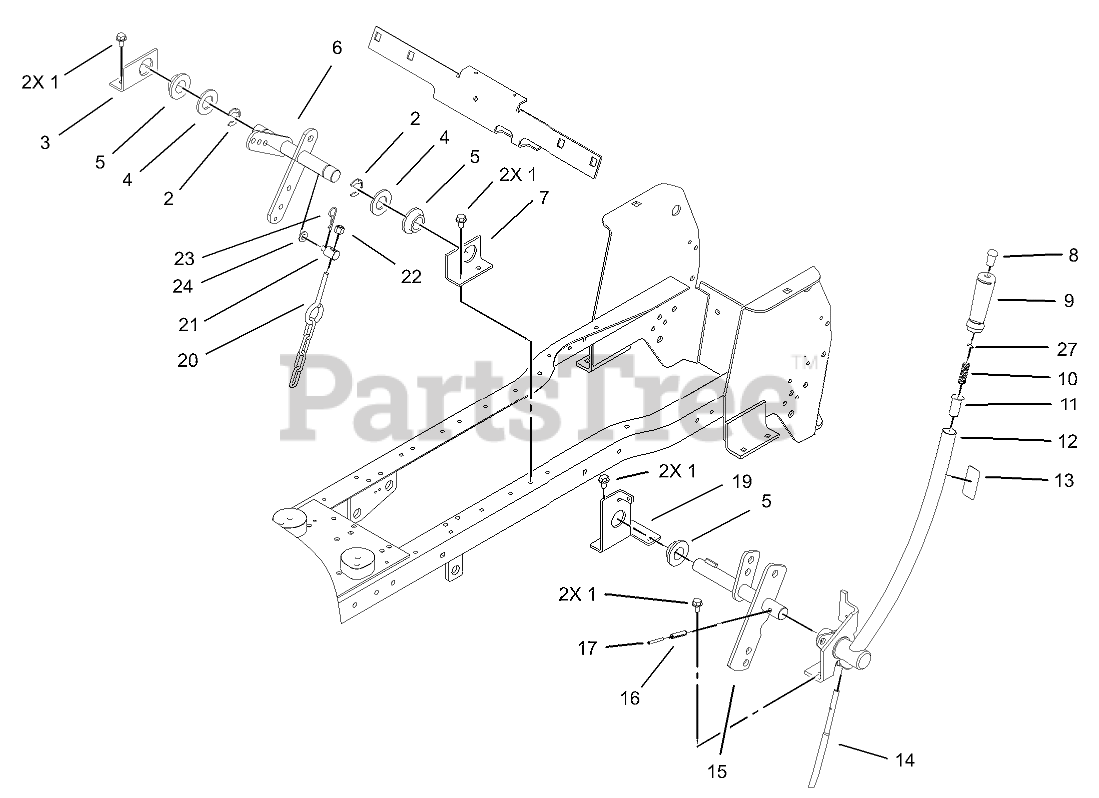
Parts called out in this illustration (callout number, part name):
1	SCREW-HWHTF
2	RING-RETAINING
3	BRACKET-PIVOT LINKAGE, RH
4	WASHER-FLAT
5	BEARING-FLANGE
6	LIFT LEVER ASM
7	BRACKET-PIVOT LINKAGE, LH
8	TIP-ROD
9	GRIP-HANDLE
10	SPRING-COMPRESSION
11	RETAINER-SPRING
12	LIFT LEVER ASM
13	DECAL-LIFT
14	ROD-LEVER, LIFT
15	LIFT ARM ASM
16	PIN-ROLL
17	PIN-SPRING
19	BRACKET-PIVOT, LIFT
20	CHAIN-LIFT
21	TRUNNION
22	NUT-LOCK, NI
23	PIN-HAIR
24	WASHER-FLAT
27	PIN-SPIROL
